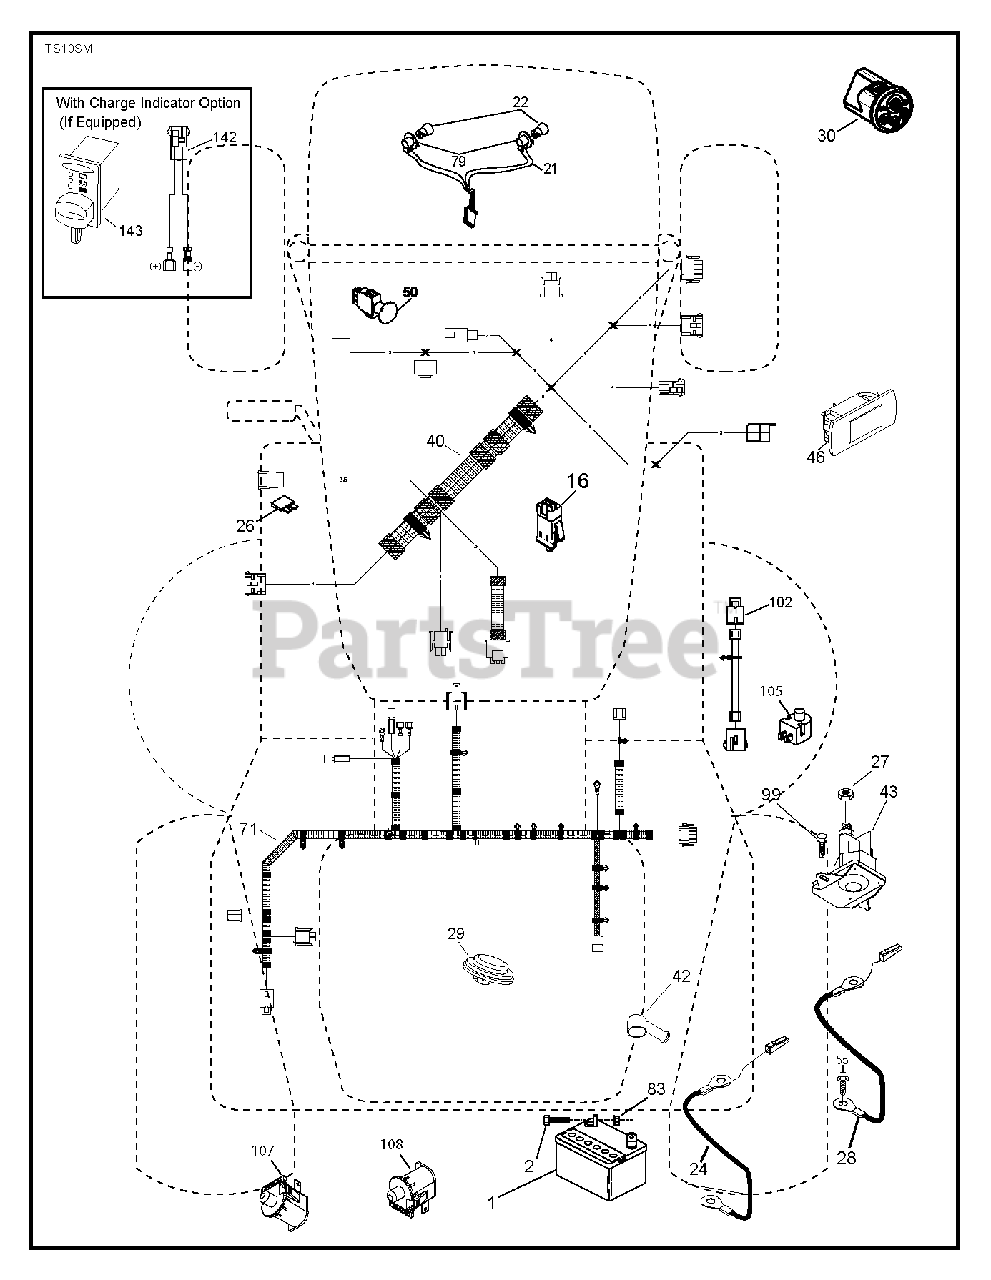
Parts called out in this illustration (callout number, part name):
1	BATTERY BATTERY 14AH 12V LEOC
2	SCREW.HEX.HEAD.CAP.M6 X1.12W
16	SWITCH INTERLOOK PUSH-IN
21	HARNESS.LIGHT W/4152J BULBS
24	CABLE.BAT.8GA.TCRD.GE
26	FUSE 20AMP
27	NUT
28	CABLE.BAT.8GA.TCRD.GE
29	SWITCH.SEAT.OPC.GRY.BUTTON/CAP
30	SMART SWITCH MY14 CRD
40	HARNESS.DASH.EL.SIS.RECT.CRD
42	TERMINAL COVER
43	SOLENOID.STARTER.BRASS.PLUNGER
46	GUAGE.SRVCMNDR.HRMTR.
50	SWITCH.PTO.8TERMINAL.STD.BLK
55	SCREW 5/16"
71	HARNESS CHAS,TEX,SIS,CRD SMART
79	BULB HOLDER ASM.
83	NUT NUT SQUARE
99	SCREW
102	HARNESS ASSY
105	REVERSE SWITCH
107	.WITCH.FULL BAGGER.INDICATOR
108	PLUNGER SWITCH (COLOR:OLIVE)
